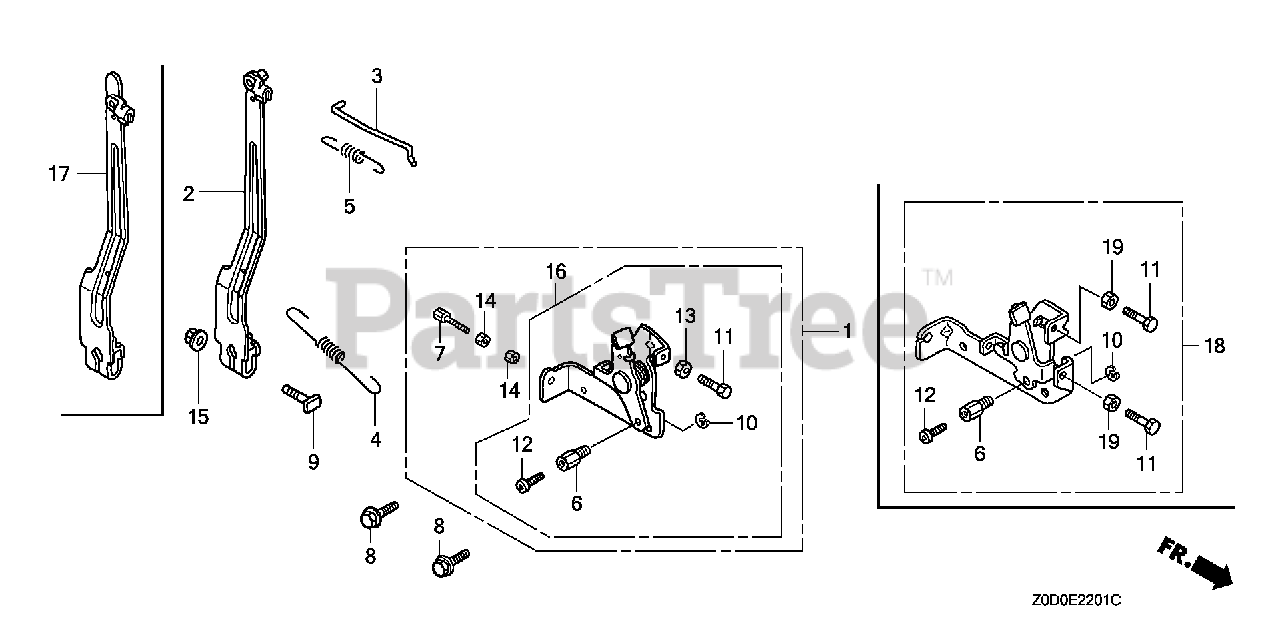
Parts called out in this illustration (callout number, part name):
2	ARM, GOVERNOR
3	ROD, GOVERNOR
4	SPRING, GOVERNOR
5	SPRING, THROTTLE RETURN
6	HOLDER, WIRE
8	BOLT, FLANGE (6X14) (CT200)
9	BOLT, GOVERNOR ARM
10	CIRCLIP (5MM)
11	BOLT, HEX. (5X20)
12	SCREW, PAN (4X6)
13	NUT, HEX. (5MM)
15	NUT, FLANGE (6MM)
16	CONTROL ASSY.
